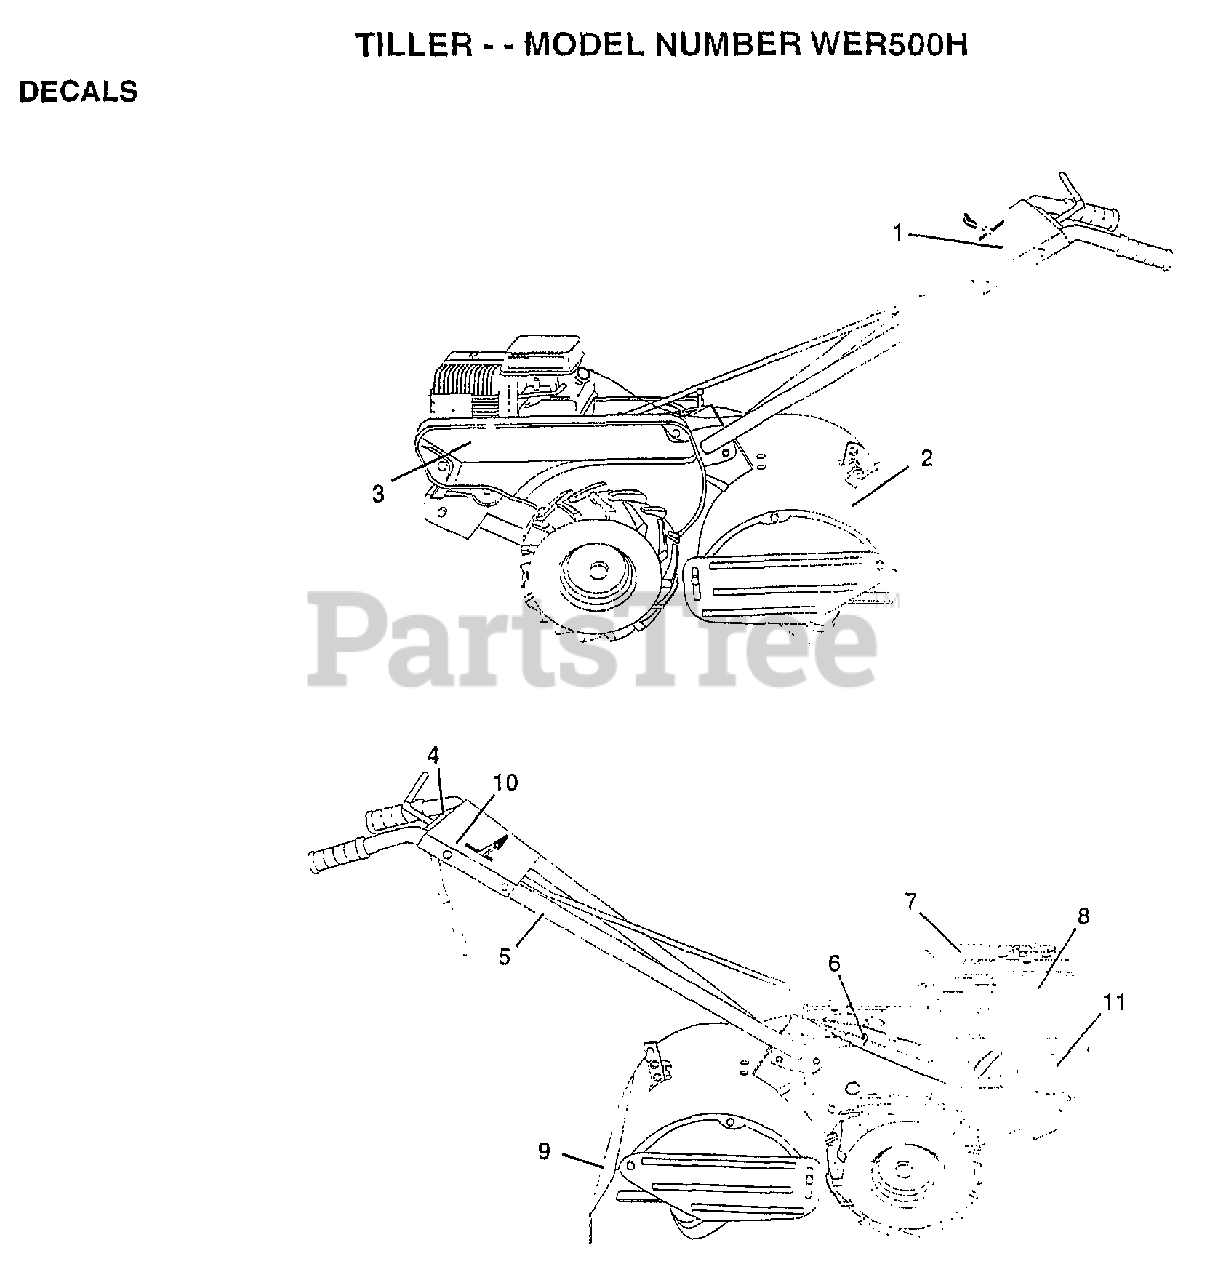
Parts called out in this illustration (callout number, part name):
1	"DECAL PANEL,CTRL"
2	DECAL SHIELD TINE
3	"DECAL GUARD,BELT"
5	DECAL TI
6	DECAL CRT
7	DECAL TI
8	DECAL, BRIGGS & STRATTON
10	DECAL REVERSE
11	DECAL, 5 HP
